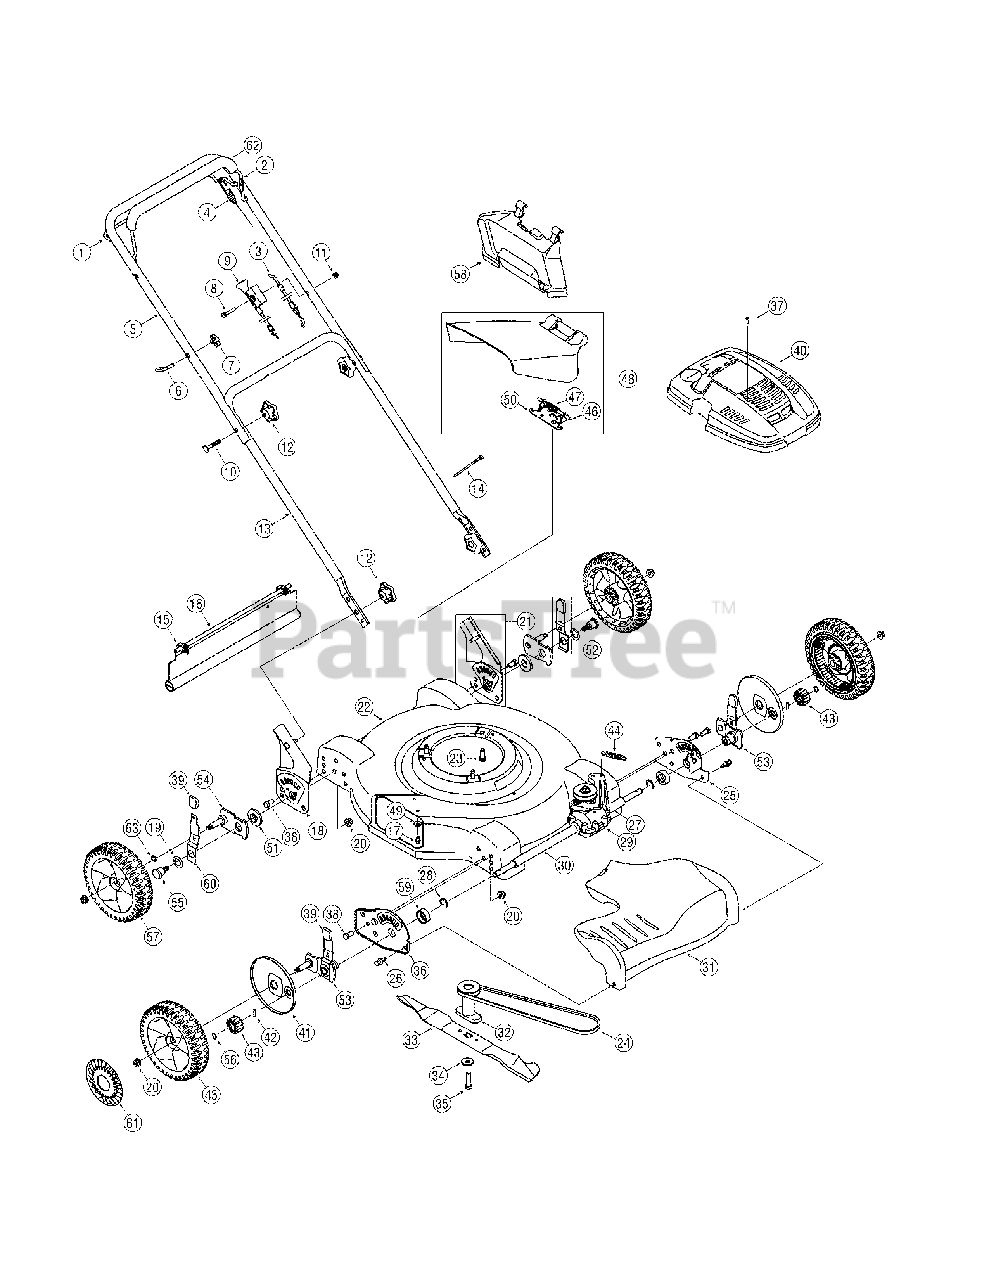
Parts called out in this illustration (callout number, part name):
1	Drive Control
2	Blade Control
3	Blade Control Cable
4	Drive Control Cable
6	Eye Bolt
7	Wing Nut, 1/4-20
8	Hex Screw, 1/4-20 x 1.50
9	Choke Cable
10	Carriage Bolt, 5/16-18 x 2.0
11	Flange Lock Nut, 1/4-20
12	Star Knob
14	Cable Tie
15	Hinge Clip
16	Trail Shield
17	Hex Screw, 1/4-20 x.500
18	Handle Bracket Assy - RH
19	Bell Washer, .760 x 1.25 x.041
20	Lock Nut, 3/8-16
21	Handle Bracket Assembly - LH
23	Hex Washer Scr., 3/8-16 x 1.0
24	V-Belt, 3L x 32.90
25	Forward Height Adj. Plate - LH
26	Rivet
27	Sleeve Spacer, .550 ID x 2.22
28	Retainer Ring
29	Transmission Assy. Comp.
30	Sleeve Spacer, .550 ID x 8.51
31	Transmission Cover (Yellow)
31	Transmission Cover
32	Blade Adapter
33	22" Mulching Blade
34	Washer, Bell, .396 x 1.140 x .095
35	Hex Cap Screw, 3/8-24 x 1.5
36	Forward Hght. Adj. Plate - RH
37	Machine Screw, M4X.7
38	Hex Cap Screw, 3/8-16 x.75
39	Adjustment Knob
40	Engine Shroud (Yellow)
40	Engine Shroud (Black)
41	Wheel Dust Cover
43	Spur Gear 14T - RH
43	Spur Gear 14T - LH
44	Ext. Spring, .47 OD x 2.50
45	Front Wheel, 8 x 1.8
45	Front Wheel, 8 x 2.125
46	Hinge Pin
47	Torsion Spring
48	Side Discharge Assembly
49	Bell Washer, .265 ID x.75 OD
50	Deflector Chute Adapter
51	Height Adjustment Bearing
52	Rear Hgt. Adj. Lever Assembly
53	Front Lever Assembly - RH
53	Front Lever Assembly - LH
54	Rear Pivot Arm Assembly
55	Shoulder Screw, 3/8-16
56	Snap Ring.500
57	Rear Wheel, 8 x 1.8
57	Rear Wheel, 8 x 2.125
58	Mulching Baffle
59	Bearing Support Spacer
60	Spring Lever
61	Hub Cap
62	Deluxe Bail Cover
63	Washer, Wave, .510 x .750 x .017
